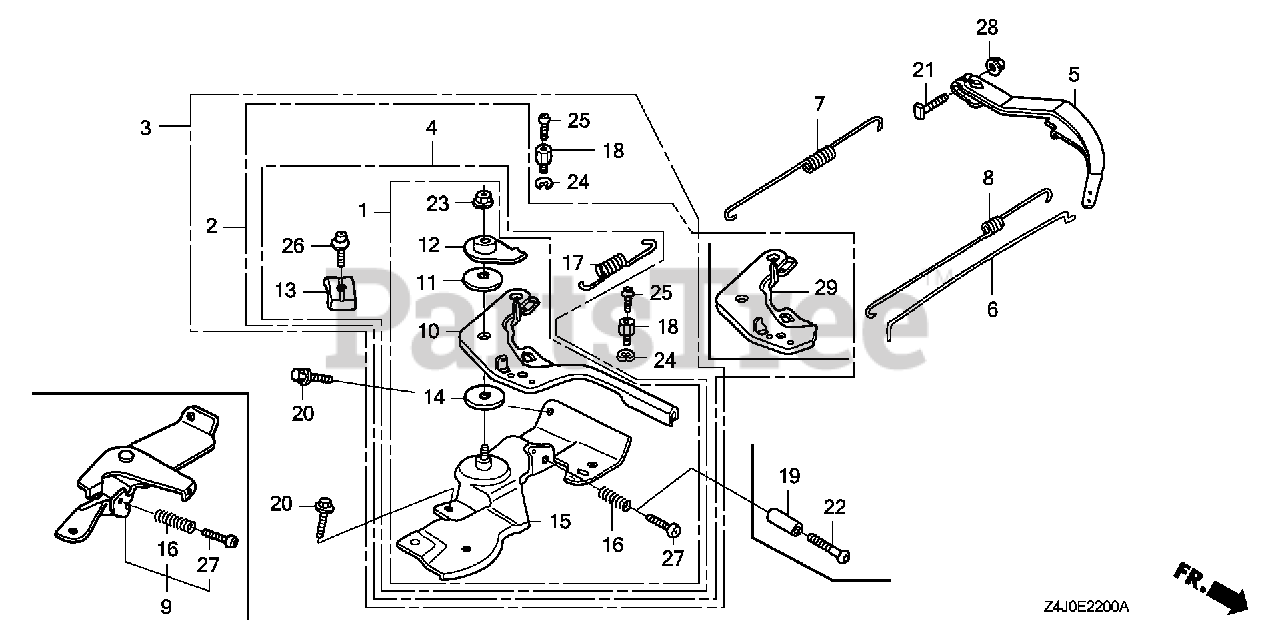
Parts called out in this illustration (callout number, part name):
5	ARM, GOVERNOR
6	ROD, GOVERNOR
7	SPRING, GOVERNOR
8	SPRING, THROTTLE RETURN
9	CONTROL ASSY.
16	SPRING, CONTROL ADJUSTING Use from Engine SN 2327377.
19	COLLAR, STOPPER
20	BOLT, FLANGE (6X12) (CT200)
21	BOLT, GOVERNOR ARM
22	SCREW, RECESSED (5X25)
27	SCREW, PAN (5X35)
28	NUT, FLANGE (6MM)
